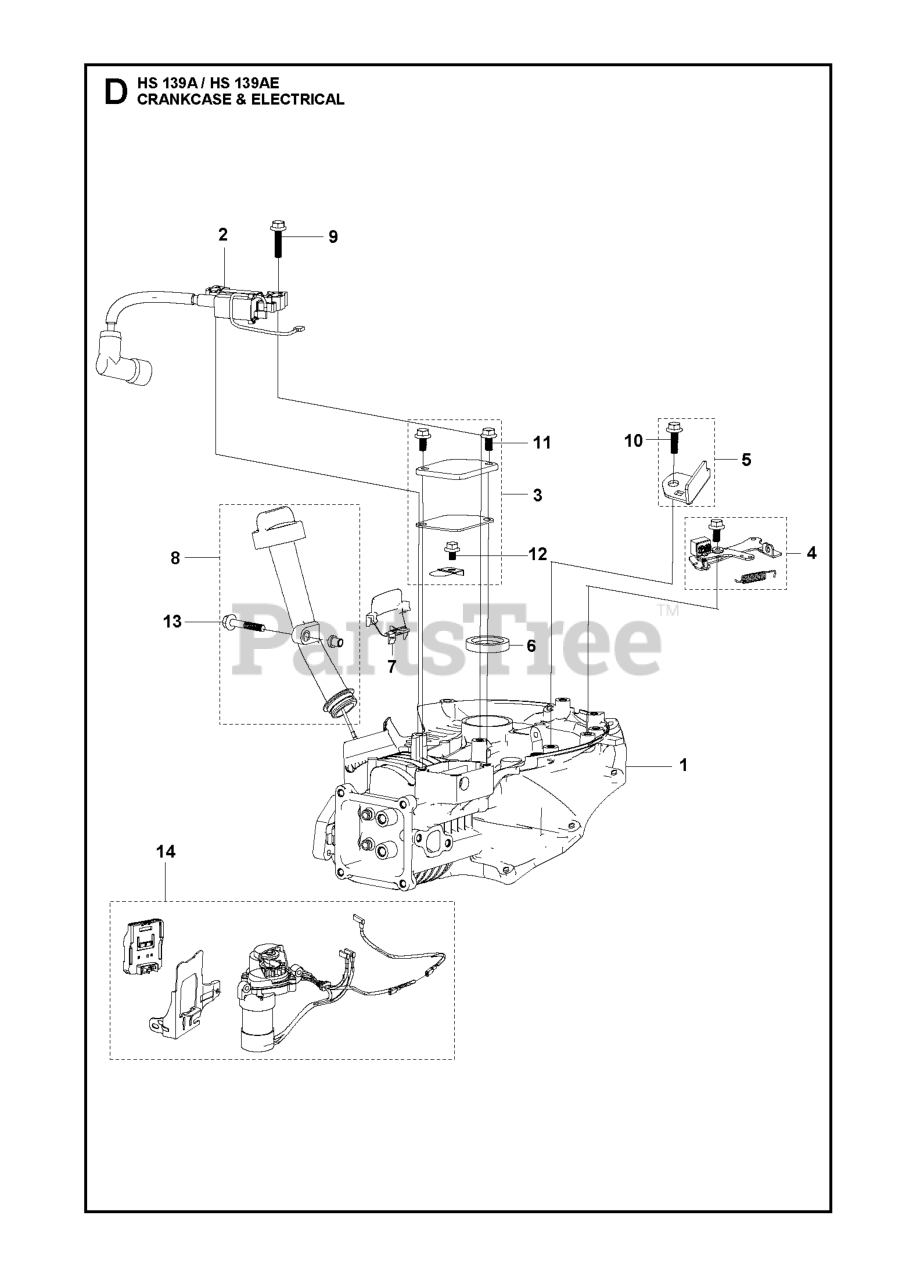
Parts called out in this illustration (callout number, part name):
9	BOLT GB/T 5789: M6 L=25
10	BOLT GB/T 5789: M6 L=20
11	BOLT GB/T 5789: M6 L=12
12	Husqvarna TBD
13	BOLT GB/T 5789: M6 L=35
